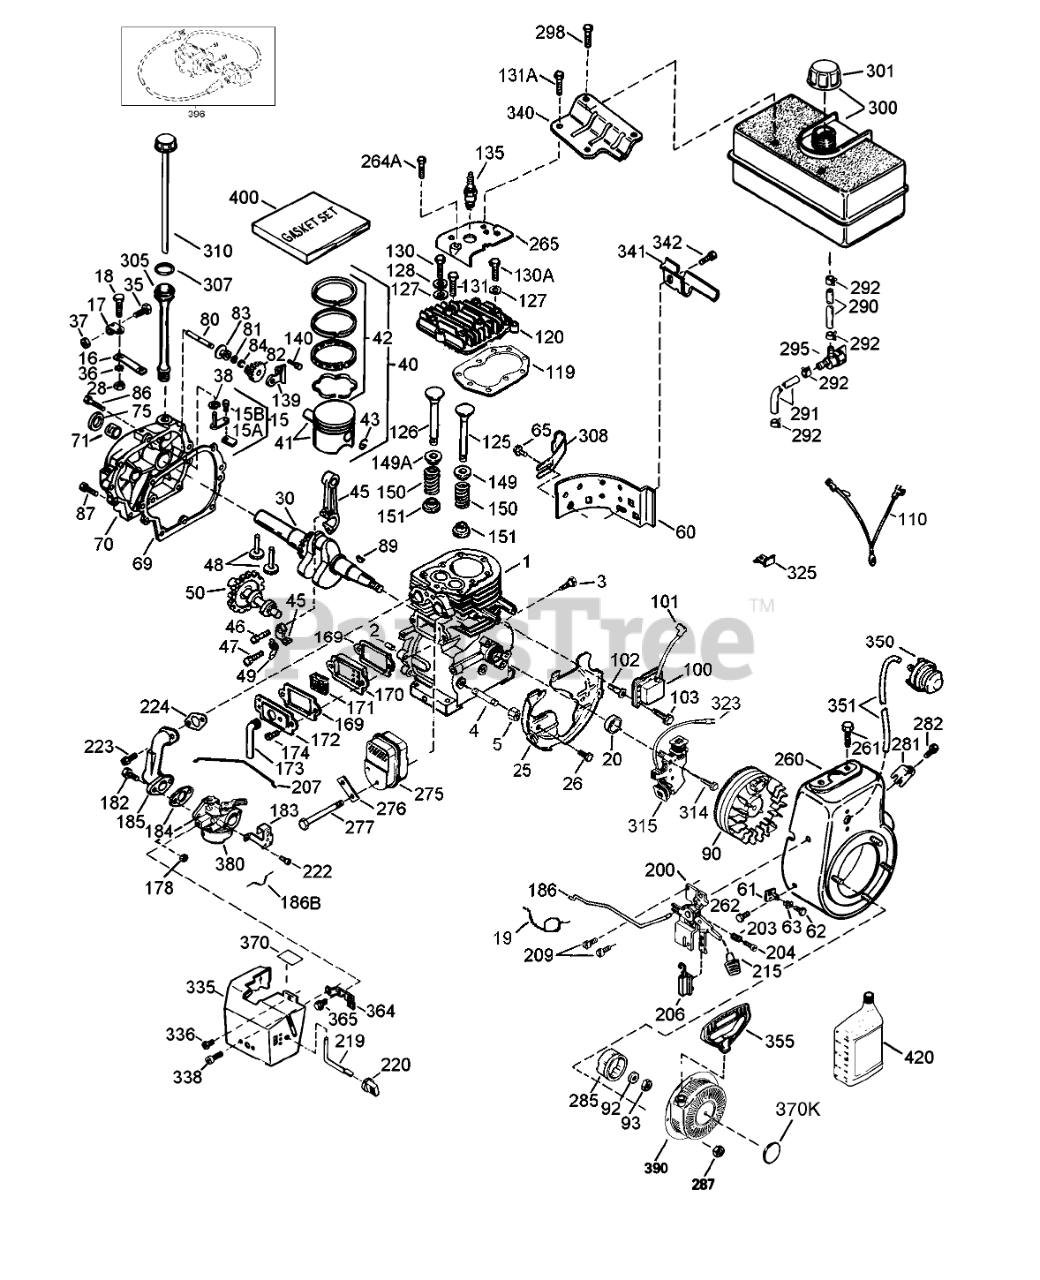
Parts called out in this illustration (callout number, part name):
1	Cylinder (Incl. ref.#2 & 20)
2	Pin-Dowel
3	Screw (1/4-20x1/2)
5	Cap-Pipe
15	Rod Assembly-Governor (Incl. ref.#15A & 15B)
15A	Yoke-Governor
15B	Screw (6-40x5/16)
16	Lever-Governor
17	Clamp-Lever, Governor
18	Screw (T-15, 8-32x7/16)
19	Spring-Throttle
20	Seal-Oil
25	Baffle-Housing, Blower
26	Screw (1/4-20x19/32)
28	Nut-Lock
30	Crankshaft
35	Screw
36	Washer-Lock
37	Nut-Lock
38	Ring-Retaining
40	Piston, Pin & Ring Assy. Std. (Includes ref.#41, 42 & 43)
41	Piston & Pin Assembly Standard (Includes ref.#43)
42	Ring Set (STD)
43	Retaining Ring-Piston Pin
45	Rod Assembly-Connecting (Incl. ref.#46, 47 & 49)
47	Bolt-Rod, Connecting
48	Lifter-Valve
49	Dipper-Oil
50	Camshaft (MCR)
60	Extension-Housing, Blower
61	Bracket
62	Screw (8-32 x 3/8)
63	Grommet
65	Screw
69	Gasket-Cover, Cylinder
70	Cover Assembly, Cylinder (Incl. ref.#71, 75 & 80)
71	Bushing-Crankshaft
72	Plug-Drain, Oil (SQH 1/4-18)
75	Seal-Oil
80	Shaft-Governor
81	Washer-Flat
82	Gear-Governor (Incl. ref.#81)
83	Spool-Governor
84	Ring-Retaining
86	Screw (1/4-20x1-3/16)
87	Screw (1/4-20x1-11/16)
89	Key-Flywheel
90	Flywheel ASM
92	Washer-Belleville
93	Nut-Flywheel
100	Solid State ASM
101	Cover-Spark Plug
102	Stud-Mounting, Solid State
103	Screw (T-15, 10-24 x 15/16)
110	Ground Wire
119	Gasket-Head, Cylinder
120	Head-Cylinder
125	Valve-Exhaust, Standard (Incl. ref.# 151)
126	Valve-Intake, Standard (Incl. ref.# 151)
127	Washer-Flat
128	Washer-Belleville
130	Screw (5/16-18x1-1/2)
130A	Screw (5/16-18x1-25/32)
131	Screw (5/16-18 X 2)
131A	Screw
135	Spark Plug-Resistor (R J19 L M)
139	Bracket-Gear, Governor
140	Screw (10-24x1/2)
149	Cap-Spring, Valve
149A	Cap-Spring, Valve
150	Spring-Valve
151	Keeper-Spring, Valve
169	Gasket-Cover, Valve
170	Body-Breather
171	Element-Breather
172	Cover-Valve
173	Tube-Breather
174	Screw
178	Nut and Lock Washer (1/4-28)
182	Screw (1/4-28x1)
183	Bracket-Choke
184	Gasket-Carburetor To Intake Pipe
185	Pipe-Intake
186	Link-Governor
186B	Spring-Choke
200	Bracket Assy.-Control (Incl. Ref.# 203, 204 & 206)
203	Spring-Compression
204	Screw (T-10, 5-40x7/16)
206	Terminal
207	Link-Throttle
209	Screw (10-32 x 1/2)
215	Knob-Control
219	Rod-Choke
220	Knob-Control
222	Screw (10-32 x 1/2)
223	Screw (T-30, 5/16-18x1-3/32)
224	Gasket-Pipe, Intake
260	Housing-Blower
261	Screw (5/16-18x3/4)
262	Screw
264A	Screw (1/2-20x5/8)
265	Cover-Cylinder Head
275	Muffler
276	Plate-Locking
277	Screw (5/16-18x4-3/16)
281	Screw
282	Screw (8-32 x 3/8)
285	Cup-Starter
287	Nut and Lock Washer (1/4-28)
290	Line-Fuel (8.62)
291	Line-Fuel
292	Clamp-Line, Fuel
295	Valve-Shut Off, Fuel
298	Screw (1/4-15x7/8)
300	Tank Assembly, Fuel (Incl. Ref.# 292 & 301)
301	Cap-Fuel
305	Tube-Fill, Oil
306	O-Ring
308	Clip-Tube, Fill
310	Gauge Oil ASM
314	Screw (1/4-20 x 3/4)
316	Coil-Alternator, 18 Watt
323	Terminal
325	Clip-Wire
327	Plug Starter
335	Cover-Carburetor
336	Screw (10-32x1/2)
338	Screw (10-32 x 3/8)
340	Bracket-Tank, Fuel
341	Bracket-Tank, Fuel (Black)
342	Screw (1/4-20x19/32)
350	Primer-Asm
351	Line-Primer
355	Handle-Starter, Mitten Grip
364	Bracket-Carburetor
365	Screw (8-32x27/64)
370	Decal-Lubrication
380	Carburetor (Incl. Ref.# 184)
390	Starter-Rewind
396	Starter-Electric (110 Volt)
400	Gasket Set (Incl. items marked )
420	Oil-Engine (SAE 5W30)
